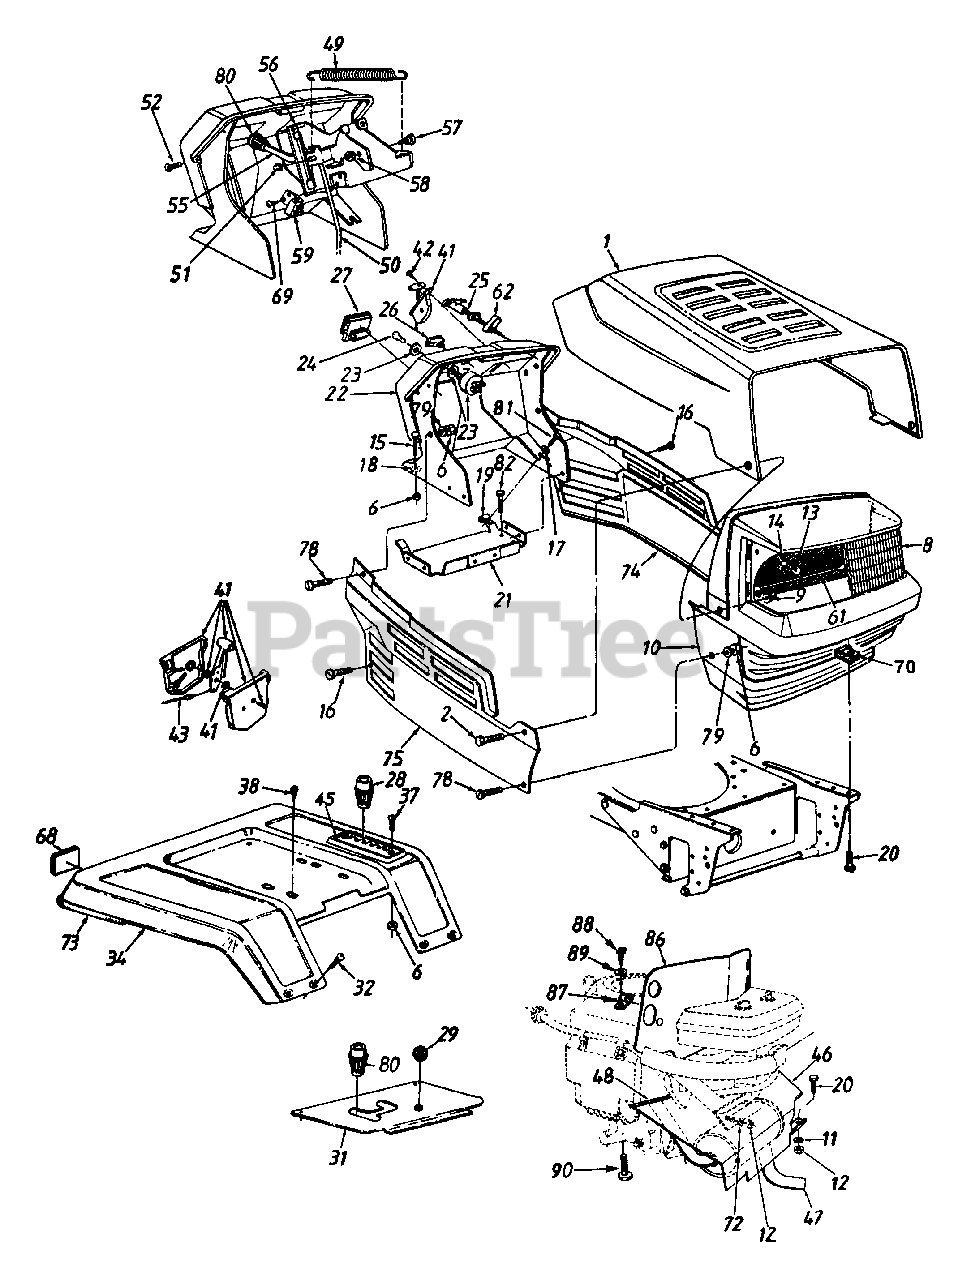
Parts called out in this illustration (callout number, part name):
6	Hex Sems Nut 1/4-20 Thd.
8	Headlight Lens
9	Flange L-Nut 1/4-20 Thd.
10	Grille
11	L-Wash. 5/16" I.D.
12	Hex Nut 5/16-18 Thd.
13	Lamp
14	Socket
15	Carriage Bolt 1/4-20 x 1.0" Lg.
16	Hex Wash. Hd. TT-Tap Scr. 1/4-20 x .5" Lg.
17	Fl-Wash. .281" I.D. x .73" O.D.
18	Bolt Retainer 1/4" I.D.
19	Speed Nut 1/4-20 Thd.
20	Hex Bolt 5/16-18 x .75" Lg.
23	Ignition Switch
24	Ignition Key
25	Choke Control
26	Light Switch
27	Ammeter
28	Shift Knob
32	Carriage Bolt 1/4-20 x .5" Lg.
38	Hex Wash. Hd. AB-Tap Scr. 5/16 x .75" Lg.
41	Throttle Box Ass'y.
42	Truss Mach. AB-Tap Scr. #10 x .5" Lg.
43	Throttle Control Wire 35" Lg.
45	6-Speed Selector Plate
46	Front Heat Shield
47	Muffler
48	Trim Strip 12" Lg.
49	Ext. Spring 5.06" Lg.
50	Deck Control Rod
51	Speed Nut 1/4" Rod
52	Torx Mach. Scr. 1/4 x .62" Lg.
55	PTO Lever
56	PTO Bracket
57	Shld. Bolt .437" Dia. x .162"
58	Hex L-Nut 5/16-18 Thd
59	Safety Switch (PTO)
61	Grille Reflector Label
62	Retainer Clip
68	Reflector
69	Hex Wash Hd. B-Tap Scr. #10 x .38" Lg.
70	U-Nut 5/16-18 Thd.
72	Spec. L-Wash. 5/16" I.D.
73	Trim Strip 81" Lg.
79	Bell-Wash. 1/4" I.D.
80	Small Shift Knob
81	Hex TT-Tap Scr. 1/4-20 x .75" Lg.
82	Hex AB-Tap Scr. 1/4 x 62" Lg.
86	Top Heat Shield
87	Clamp
88	Truss Mach. Scr. #10 x 5" Lg.
89	Fl-Wash. .188" I.D. x .43" O.D.
90	Hex L-Wash. TT-Tap Scr. 3/8-16 Thd.
